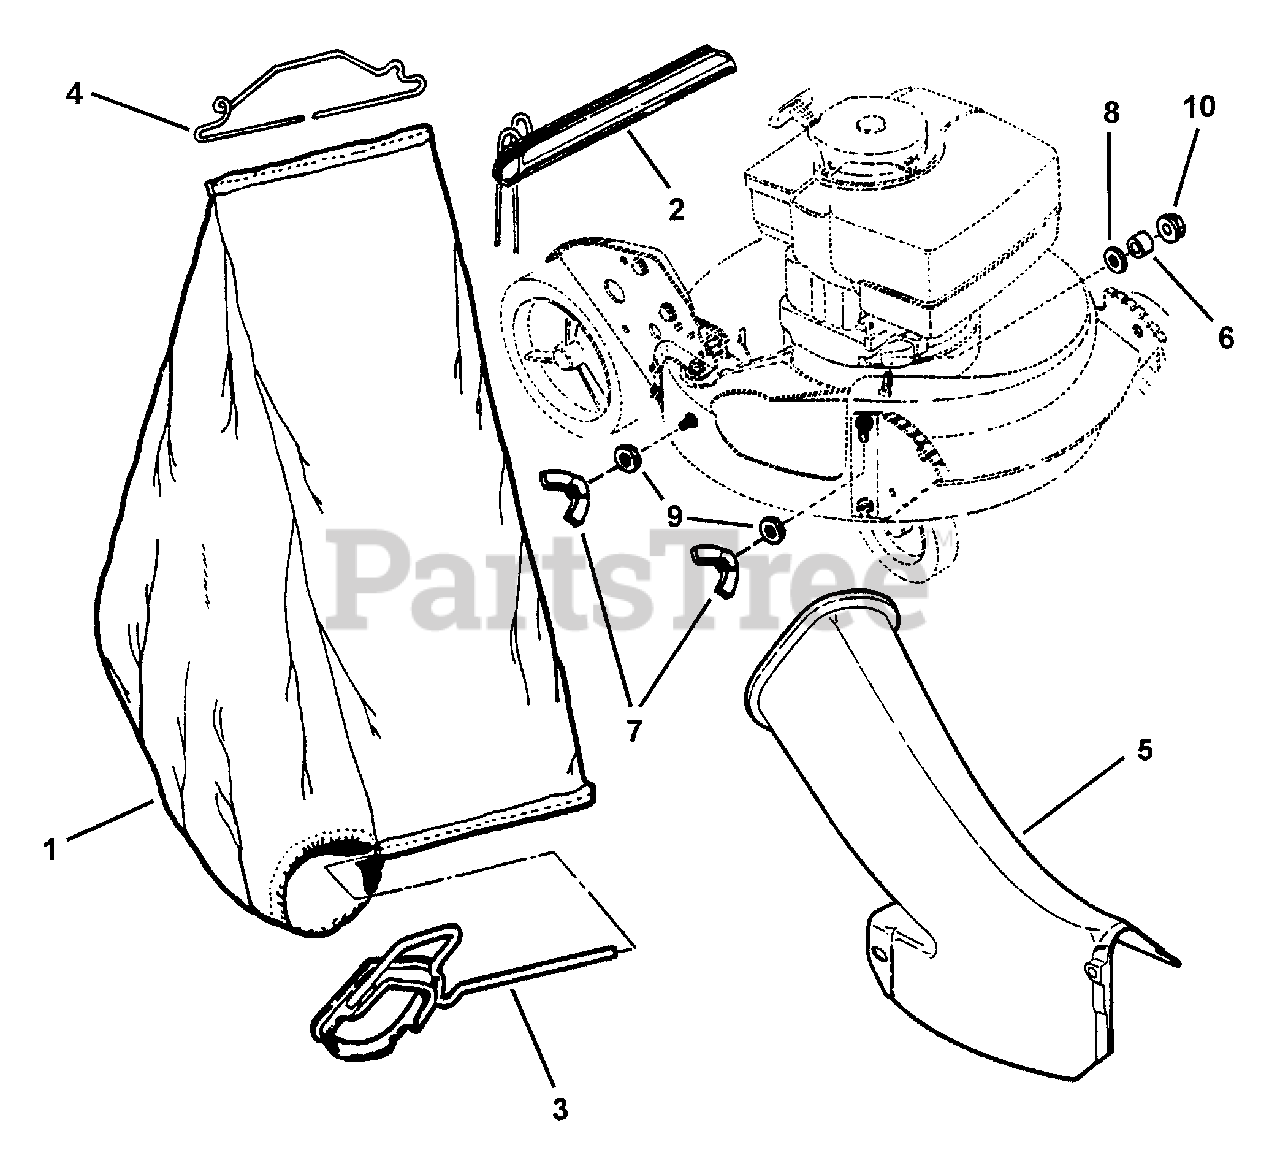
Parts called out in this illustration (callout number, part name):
1	BAG, Grass Slider (Black/Gold) (10.75" Wide)
1	BAG, Grass Slider (Black/Gold) (11.25" Wide)
2	ASSEMBLY, Slider
3	CONNECTOR, Grass Bag
4	WIRE, Bag Connector (12" Wide)
4	WIRE, Bag Connector (14" Wide)
5	ADAPTER, Bag
6	SPACER
7	NUT, 5/16-18 Wing (Nylon Patch)
8	RETAINER, 5/16 Bolt
9	WASHER, 5/16 Flat
10	NUT, 5/16-18 Hex Flange Center Lock
